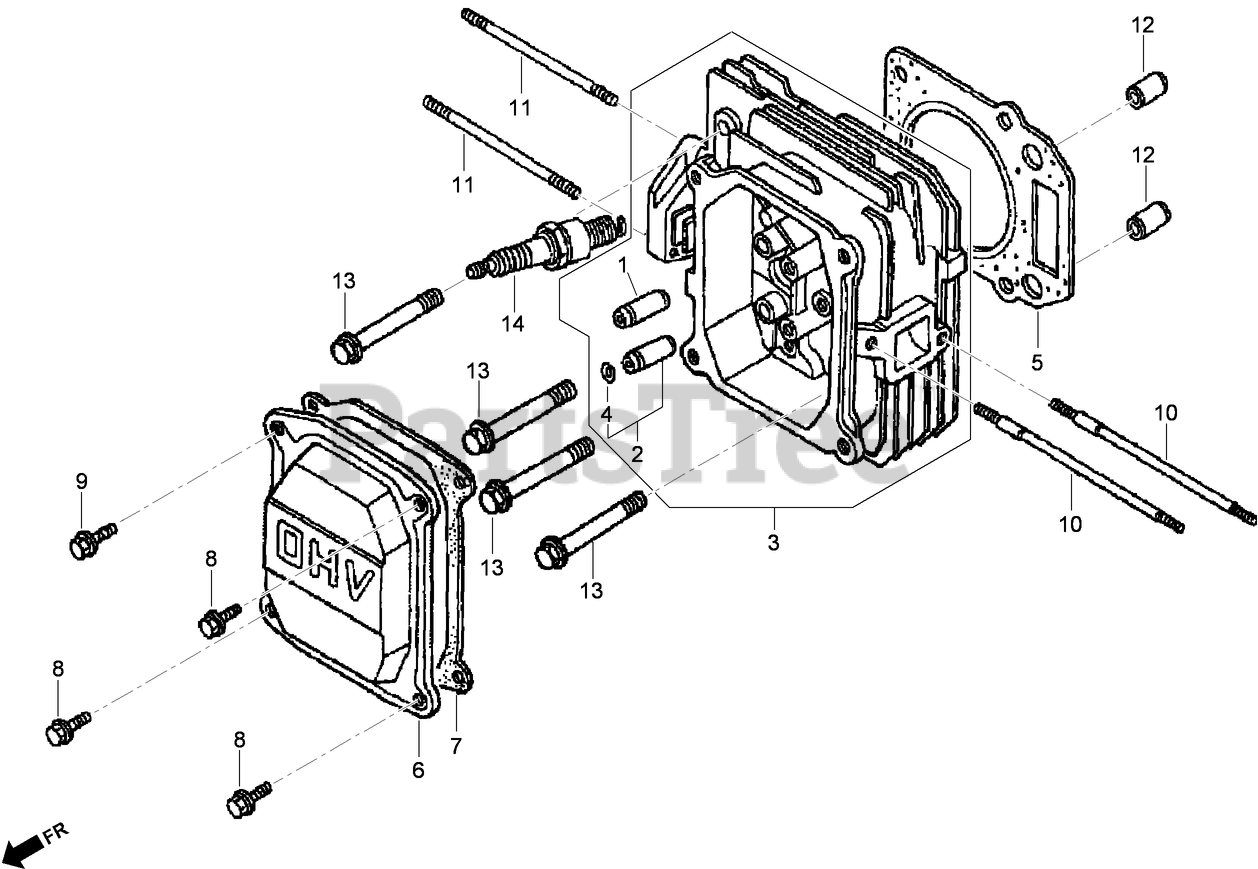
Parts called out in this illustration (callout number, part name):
1	GUIDE-VALVE (O S)
2	GUIDE-VALVE, EXHAUST (O S)
3	HEAD-CYLINDER
4	CLIP-GUIDE, VALVE
5	GASKET-HEAD, CYLINDER
6	Cover-Head
7	GASKET-COVER, CYLINDER HEAD
8	BOLT-FLANGE (6X12) (C T200)
8	BOLT-FLANGE (6X14) (C T200)
9	BOLT-FLANGE (6X14) (C T200)
10	BOLT-STUD (6X109)
11	BOLT-STUD (6X85)
12	PIN-DOWEL (10X16)
13	BOLT-FLANGE (8X50)
14	SPARK PLUG (B P R4E S) (N G K)
14	SPARK PLUG (W14E P R-U) (DENSO)
14	SPARK PLUG (B P R 5E S) (N G K)
14	SPARK PLUG (W16E P R-U) (DENSO)
14	SPARK PLUG (B P R 6E S) (N G K)
14	SPARK PLUG (W20E P R-U) (DENSO)
